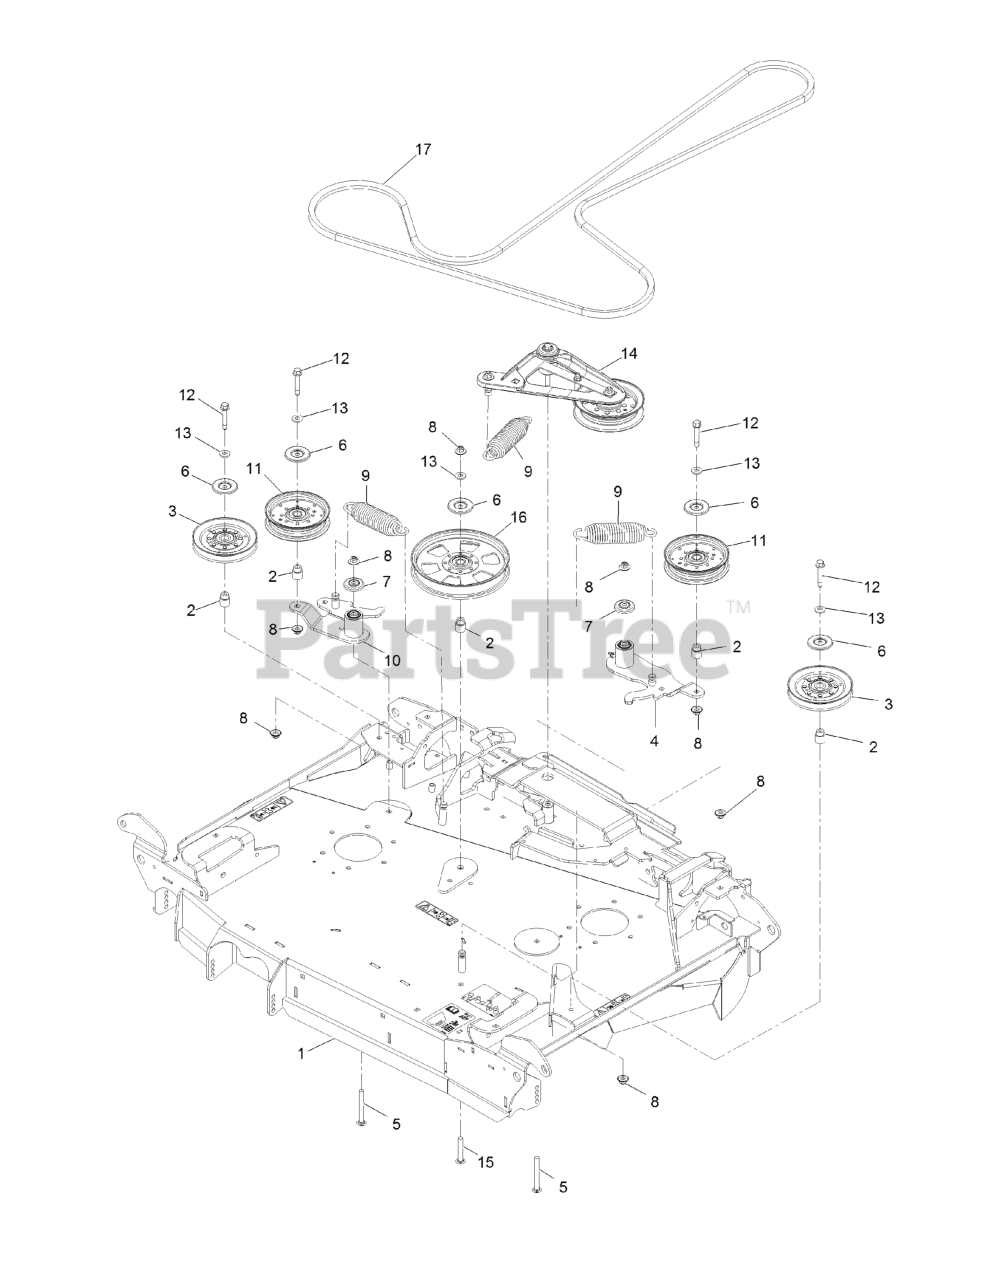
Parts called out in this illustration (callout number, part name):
1	ASM-DECK, CTR 96
2	BUSHING-IDLER
3	IDLER-V
4	IDLER ASM
5	BOLT-SHOULDER, CARRIAGE 3/8-16 X 3 1/2
6	SHIELD-DUST
7	GUARD-TOP
8	Nut-Nyloc 3/8-16 Flg
9	SPRING-EXTENSION
10	IDLER ASM
11	PULLEY-IDLER, FLAT
12	SCREW-HHF
13	WASHER-BELLEVILLE
14	DECK IDLER ASM
15	SCREW-CARR
16	PULLEY-IDLER, FLAT
